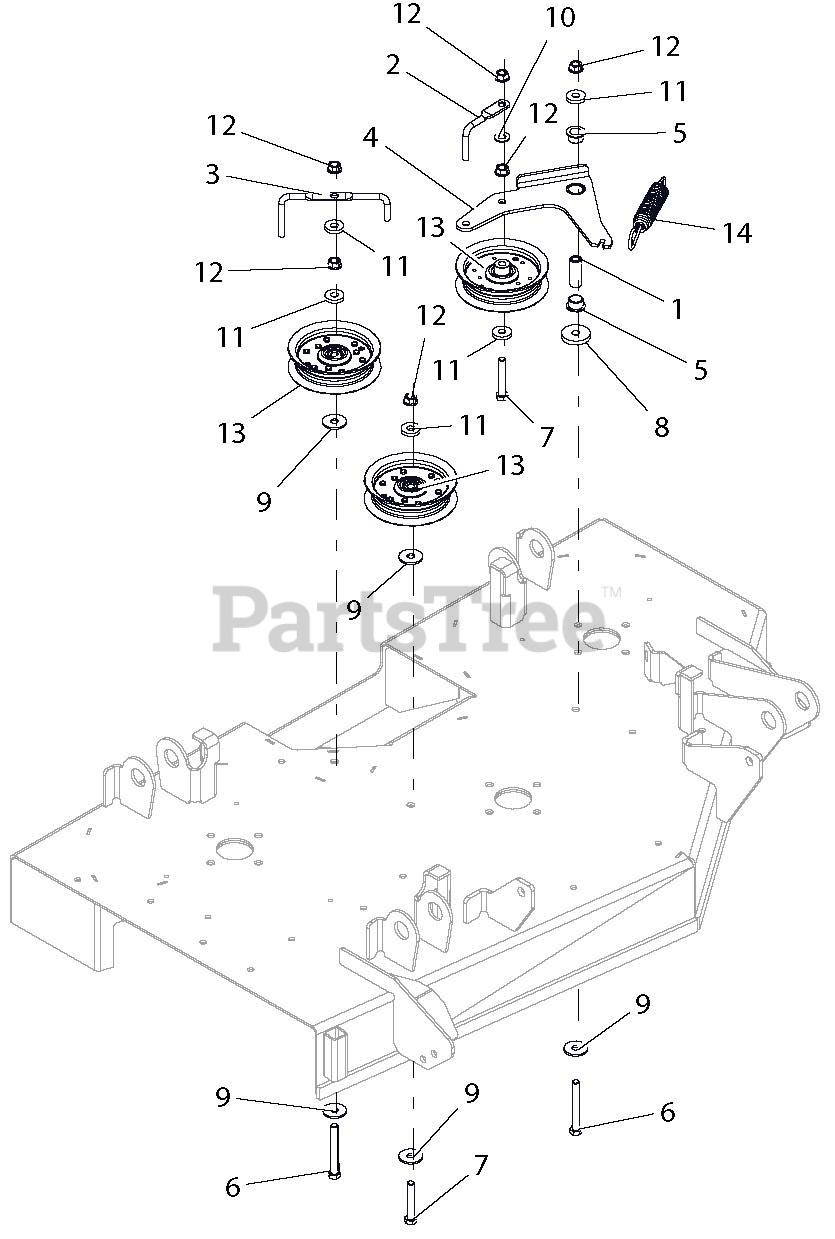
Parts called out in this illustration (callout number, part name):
1	SPACER, .375IDX.625ODX1.66 PM
2	WIREFORM, BELT FINGER
3	WIREFORM, BELT FINGER
4	WLDMT, IDLER ARM-42"
5	BSHG-FLG, .625X.750X.500X1.00
6	BLT-HEX .38-16X3.00 GR5 FTH YZ
7	@BLT-HEX .38-16X2.25 GR5 YWZC
8	WSHR,FLT STL.406X1.50X.245YWZC
9	@WSHR-FL-STL .406X1.25X.10 ZC
10	@WSHR-FL-STL.406X.812X.065 YWZ
11	WSHR-FL-STL .406X1.00X.188 YWZ
12	@NUT-LK-TOP-FLG .38-16 YWZC
13	ASM, IDLER 4"
14	SG-TENS .135X.98X6.0 WLD 62
